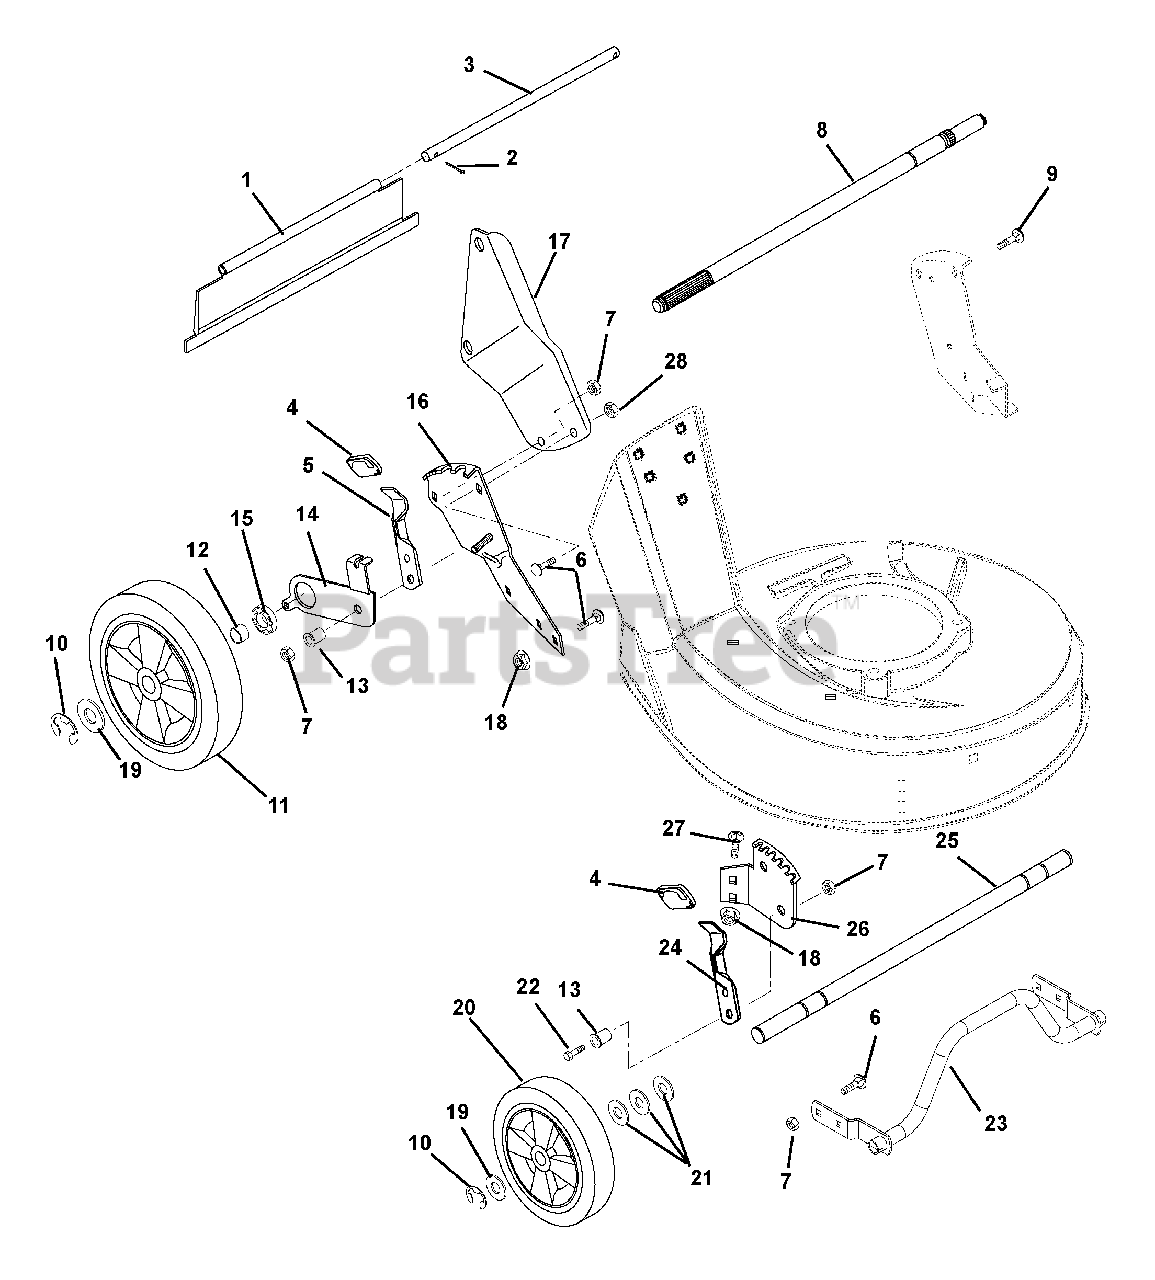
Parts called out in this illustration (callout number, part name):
1	REAR PROTECTIVE GUARD, S.P.
2	PIN-CTR .06X.50 EXTPRSQCT YWZ
3	ROD
5	HEIGHT ADJUSTMENT LEVER
6	BLT-RHDSSQNK .31-18X.62 G5YZ
7	NUT-LK-CTR .31-18 YWZC
8	REAR AXLE,5/8 DIA
9	BLT-RDHDSQNK .31-18X1.0 SHTYZ
10	RG-RTNG-EXT .500X.042 (E)
11	WHL, LH 10.50"
11	WHL, RH 10.50"
11	10 1/2 TIRE SKIN
12	SPACER TUBE, SELF PROPEL
13	BSHG-FLG .32X.500X.344X.880
14	REAR ADJUSTMENT BRACKET L.H.
14	REAR ADJUSTMENT BRACKET R.H.
14	REAR BRACKET & BEARING ASSY RH
15	BRG-BALL .625X1.383X.50
16	QUADRANT, REAR LH
16	QUADRANT, REAR RH
17	RH HANDLEBAR MOUNT WELDMENT
17	LH HANDLEBAR MOUNT WELDMENT
18	NUT-SPNLK-FLG .312-18 YWZC
19	WSHR-FL-STL .505X.880X.072 YWZ
20	WHL 7.50" .50 BORE, 1.50 HUB
21	WSHR-FL-STL .52X.827X.062 YWZC
22	BLT-HEX .31-18X1.00 GR5 YWZC
23	GUARD, LM VALVE COVER
24	FRONT HEIGHT ADJUSTMENT LEVER
25	FRONT AXLE
26	FRONT QUADRANT, LH
26	FRONT QUADRANT, RH
27	BLT-RDHDSQNK .31-18X.50 G5YZ
28	NUT-LK-NYL .312-18 YWZC
